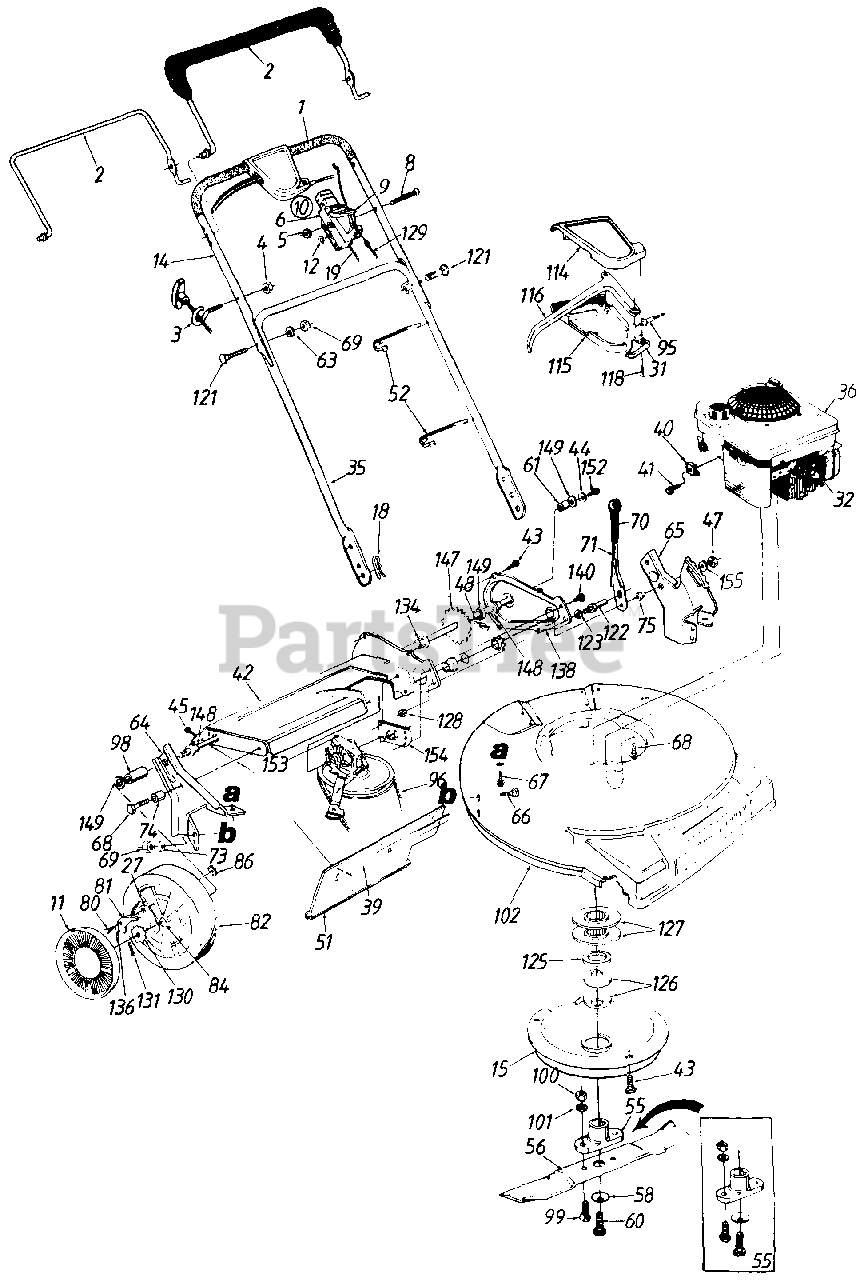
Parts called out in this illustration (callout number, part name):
1	Grip
2	Control Handle
4	Hex L-Nut 1/4-20 Thd.
5	Hex L-Nut 1/4-20 Thd.
6	Throttle Body
8	Oval C-Sunk Scr.
9	Throttle Lever
10	Throttle Box Comp.
11	Hub Cap
12	Spr. Wash. .66" I.D.
19	Throttle Control Wire 55" Lg.
27	Pawl Plate
31	S.P. Control Cover
32	Spark Plug Insulator
35	Lower Handle
36	Engine
39	Retaining Strip
40	Cable Clamp
41	Hex Self-Tap Scr. #10-32 x .62"
42	Chain - Axle Ass'y.
43	Hex B-Tap Scr. 1/4" x .38"
44	Bell-Wash. 1/4" I.D.
45	Hex AB-Tap Scr. 1/4 x .62"
47	Hex Patch L-Nut 3/8-24 Thd.
48	#48 Chain .500" Pitch x 38 Links
51	Rear Flap 3.75" x 17.30" Lg.
52	Cable Tie
55	Blade Adapter Kit
56	21" Mulching Blade
58	Bell-Wash. .47" I.D. x 1.14" O.D.
60	Hex Bolt 7/16-20 x 2.5"
61	Spacer, .513" I.D.
63	L-Wash, 5/16" I.D.
64	R.H. Handle Wheel Brkt. Ass'y.
65	L.H. Handle Wheel Brkt. Ass'y.
66	Carriage Bolt 5/16-18 x .62"
67	Hex B-Tap Scr. 5/16-18
68	Hex TT-Tap Scr. 3/8-16
69	Hex Nut 5/16-18 Thd.
71	Height Adj. Lever
73	Bell-Wash. 5/16" I.D.
74	Spacer .383" I.D.
75	Shld. Spacer .5" Dia.
80	Shld. Scr. .342" Dia. x .268
81	Pawl
82	Wheel Ass'y. Comp. - Rear
84	Sleeve Bearing 1/2" I.D.
86	Weld Top L-Nut 1/4-20 Thd.
95	S.P. Cable - 44" Lg.
96	"V"-Belt
98	Sleeve .526" I.D.
99	Hex Bolt 3/8-24 x 1.0" Lg.
100	Hex Nut 3/8-24 Thd.
101	L-Wash. 3/8" I.D.
115	Self-Propelled Control Cover
116	Control Lever
118	Fl-"C"-Sunk Hd. Tap Scr. #10 x .75" Lg.
121	Curved Carr. Bolt 5/16-18 x 1.38" Lg.
122	Shld. Pin 1.43" Lg.
123	L-Wash. 3/8" I.D.
125	Crankshaft Spacer
126	Bell-Wash. 1.01" I.D.
127	Pulley Half - Serrated
128	Hex Jam Nut 3/8-24 Thd.
129	Control Cable - 39"
130	Ratchet Wheel 1.62" O.D.
131	Cotter Pin 1/8" Dia. x 1"
134	Hex Flange Bearing
136	Spring - Nylon
147	Rear Shaft Ass'y. 21.44" Lg.
148	Hex Flange Brg. .506" I.D.
149	Fl-Wash. .531" I.D. x .930"
152	Hex Bolt 1/4-20 x .62" Lg. (Grade 5)
153	Transmission Comp.
155	Fl-Wash. .385" I.D. x .87" O.D.
